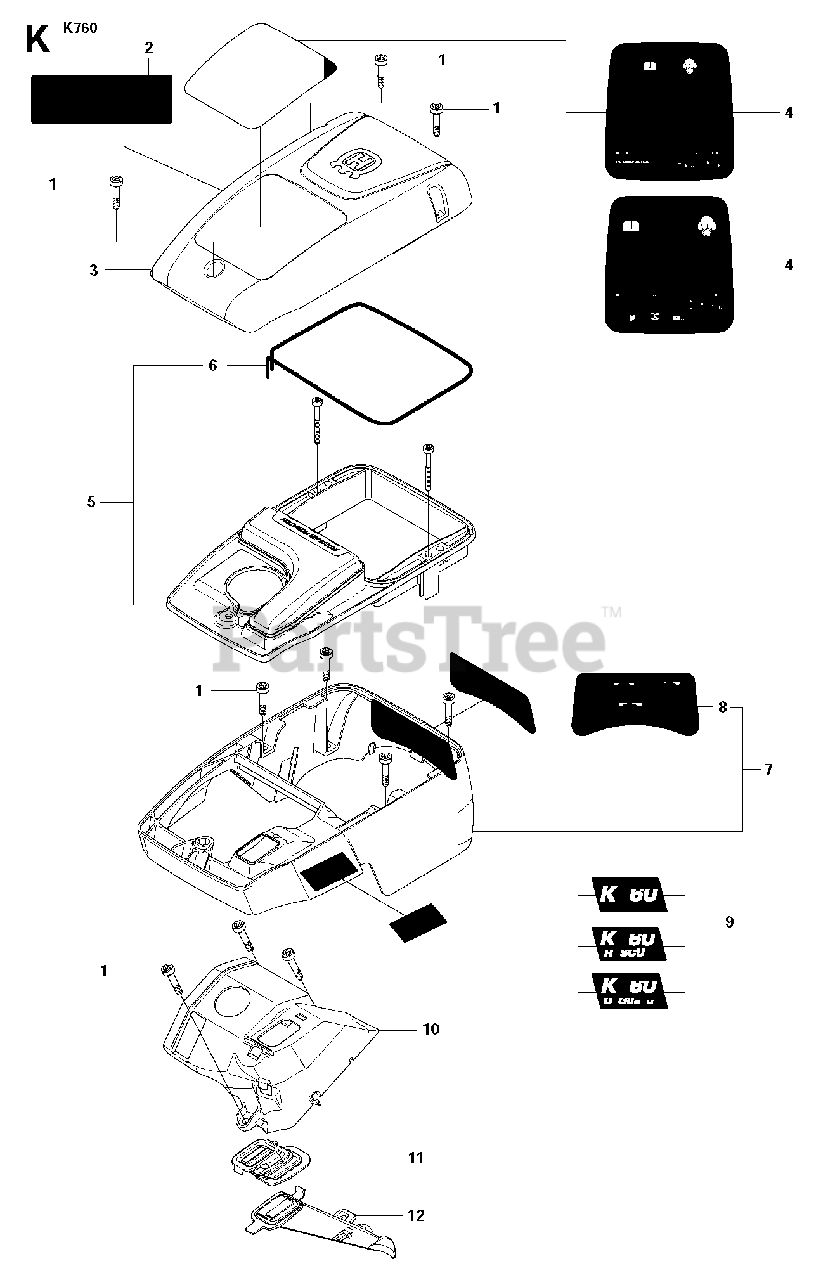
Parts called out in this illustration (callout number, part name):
1	SCREW ITXSCM
3	FILTER COVER
4	DECALEPA USA
4	DECALCE, EPA Canada
5	FILTER HOLDER ASSYIncl. 6
5	FILTER HOLDER ASSYOIL GUARD
6	SEALING STRIP
7	CYLINDER COVER ASSYIncl. 8
9	DECALOil Guard
10	COVERIncl. 12, 13
11	BELLOWS
